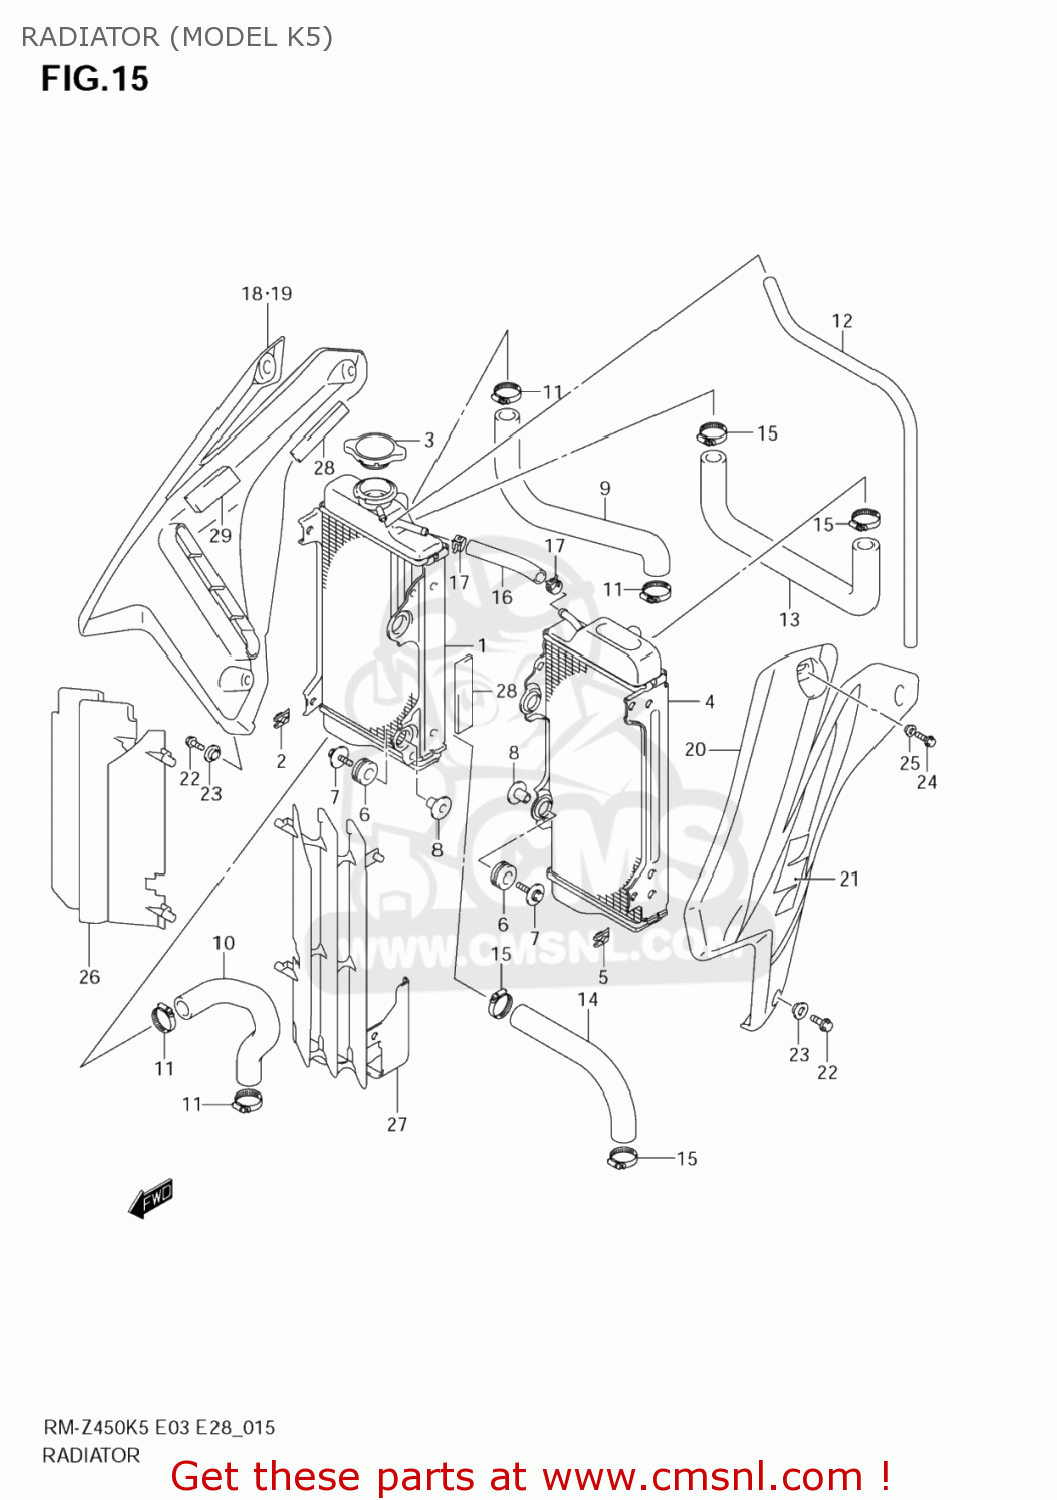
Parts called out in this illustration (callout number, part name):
1	RADIATOR,WATER,R
2	NUT
3	CAP COMP,RADIATOR
4	RADIATOR,WATER,L
5	NUT
6	CUSHION,RADIATOR LWR
7	BOLT(6X25)
8	SPACER(6.5X10.5X14.1)
9	HOSE,RADIATOR INLET
10	HOSE,RADIATOR OUTLET
11	CLAMP
12	HOSE(5X8X2000)
13	HOSE,RADIATOR JOINT UPR
14	HOSE,RADIATOR JOINT LWR
15	CLAMP
16	HOSE,RADIATOR BYPASS
17	CLIP
18	COVER,RADIATOR,R(YELLOW)
19	TAPE,RADIATOR COVER,R
20	COVER,RADIATOR,L(YELLOW)
21	TAPE,RADIATOR COVER,L
22	BOLT(6X12)
23	WASHER,RR BRAK
24	BOLT(6X16)
25	SPACER(6.3X10X6)
26	LOUVER,RADIATOR,R
27	LOUVER,RADIATOR,L
28	CUSHION,RADIATOR
29	CUSHION,RADIATOR COVER NO.2
